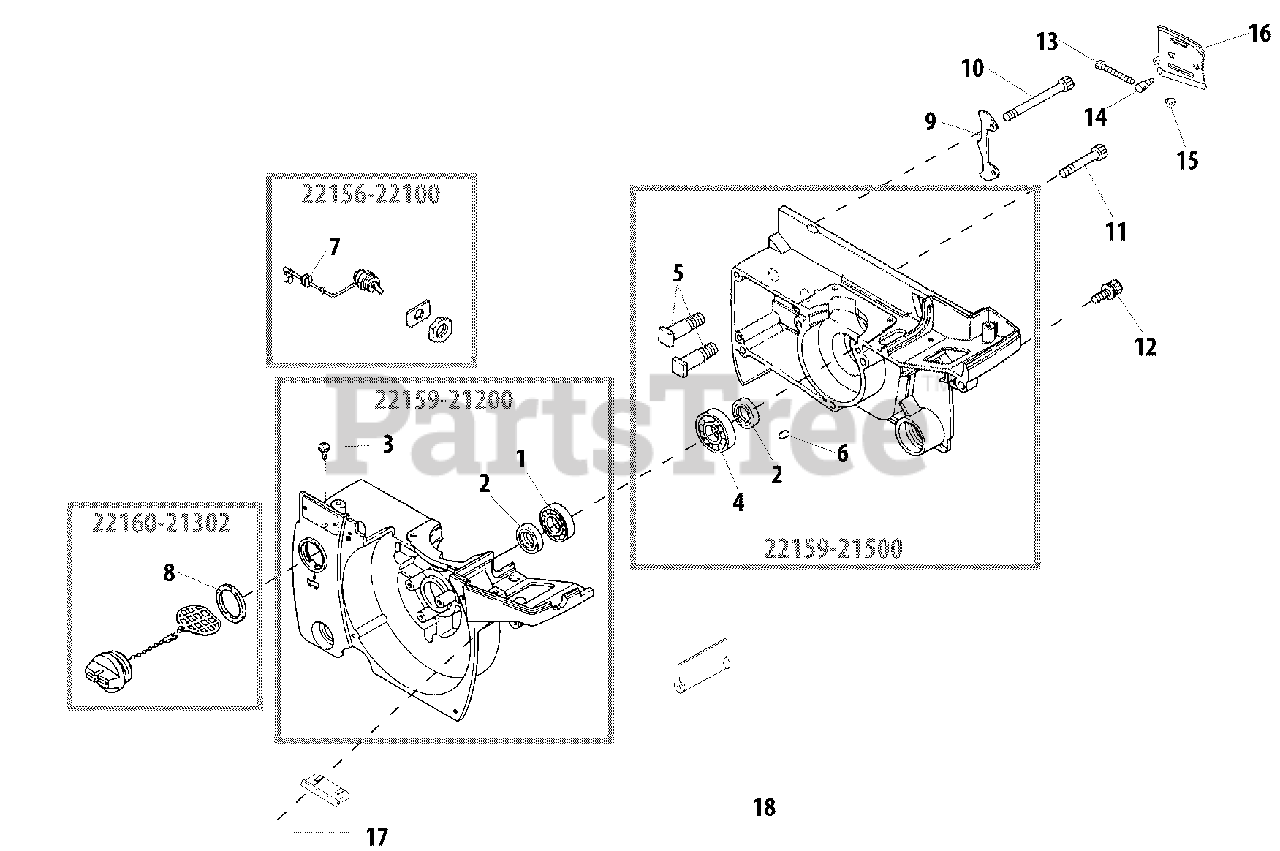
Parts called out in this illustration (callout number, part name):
1	BEARING, BALL 6001 C3
2	SEAL, OIL 12
3	VENT ASSY
4	BEARING, BALL 6201 C3
5	STUD, GUIDE BAR
6	PIN, DOWEL
8	GASKET, CAP
9	SPIKE, BUMPER
10	BOLT
11	BOLT 5×30
13	SCREW, SLIDE
14	TENSIONER, CHAIN
15	NUT, PUSH
16	PLATE, GUIDE A
17	STOPPER, SHUTTER
18	PLATE, SHUTTER
22156-22100	SWITCH ASSY, ON-OFF
22159-21200	CRANKCASE ASSY - FRONT
22159-21500	CRANKCASE ASSY - RIGHT
22160-21302	CAP ASSY, OIL
